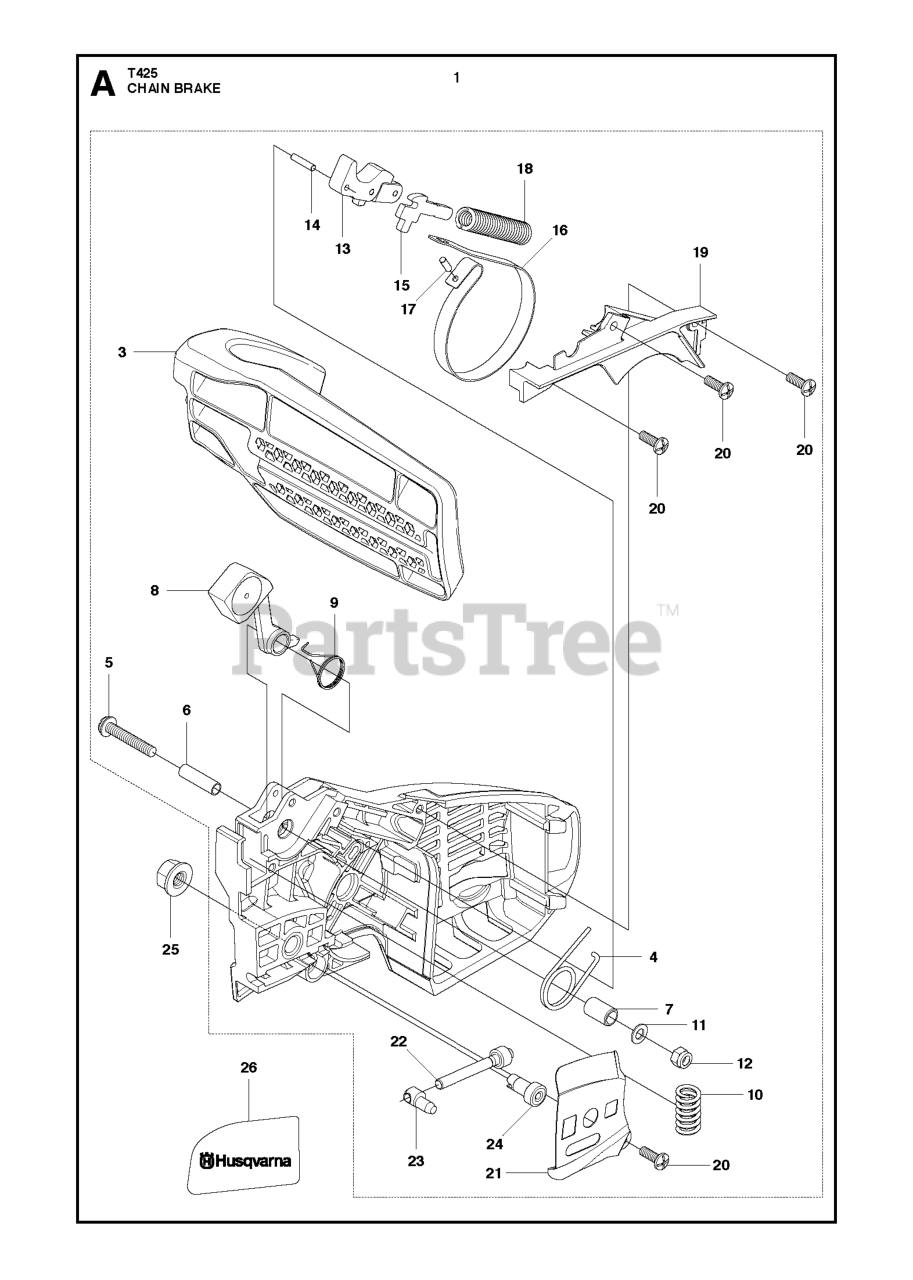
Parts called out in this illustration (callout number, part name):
12	NUT
15	ARM
18	SPRING
